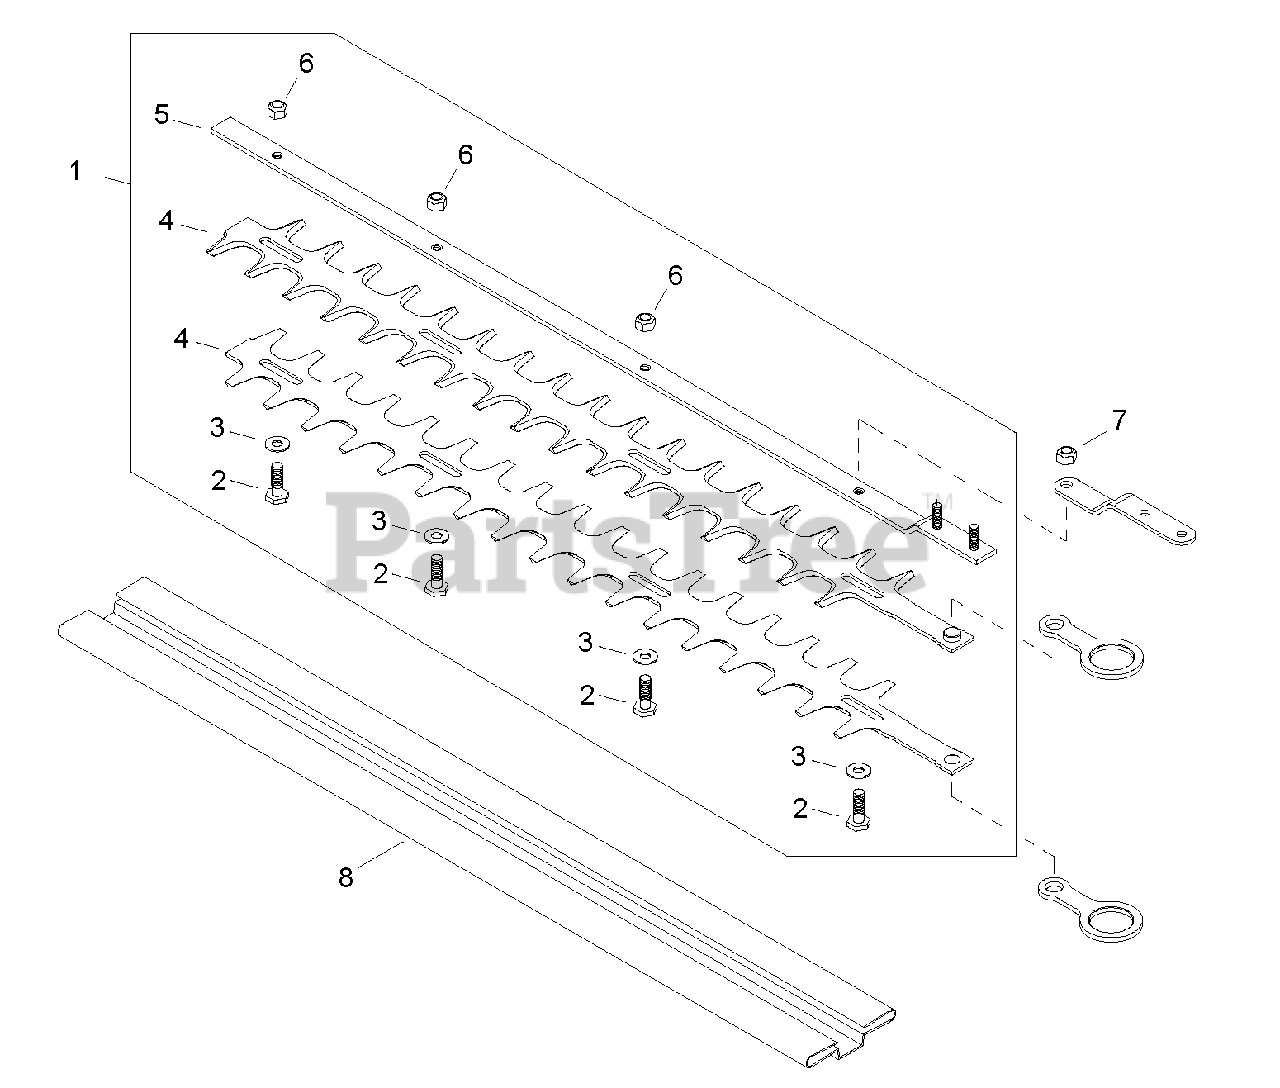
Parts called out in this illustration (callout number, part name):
1	BLADE KIT - 22" (55cm) CHROME
2	BOLT - 6X20
3	WASHER - 6
4	BLADE KIT - 22" (55cm) CHROME
5	GUIDE BAR - 22" (55cm)
6	LOCKNUT - 6
7	LOCKNUT - 6
8	COVER, BLADE
